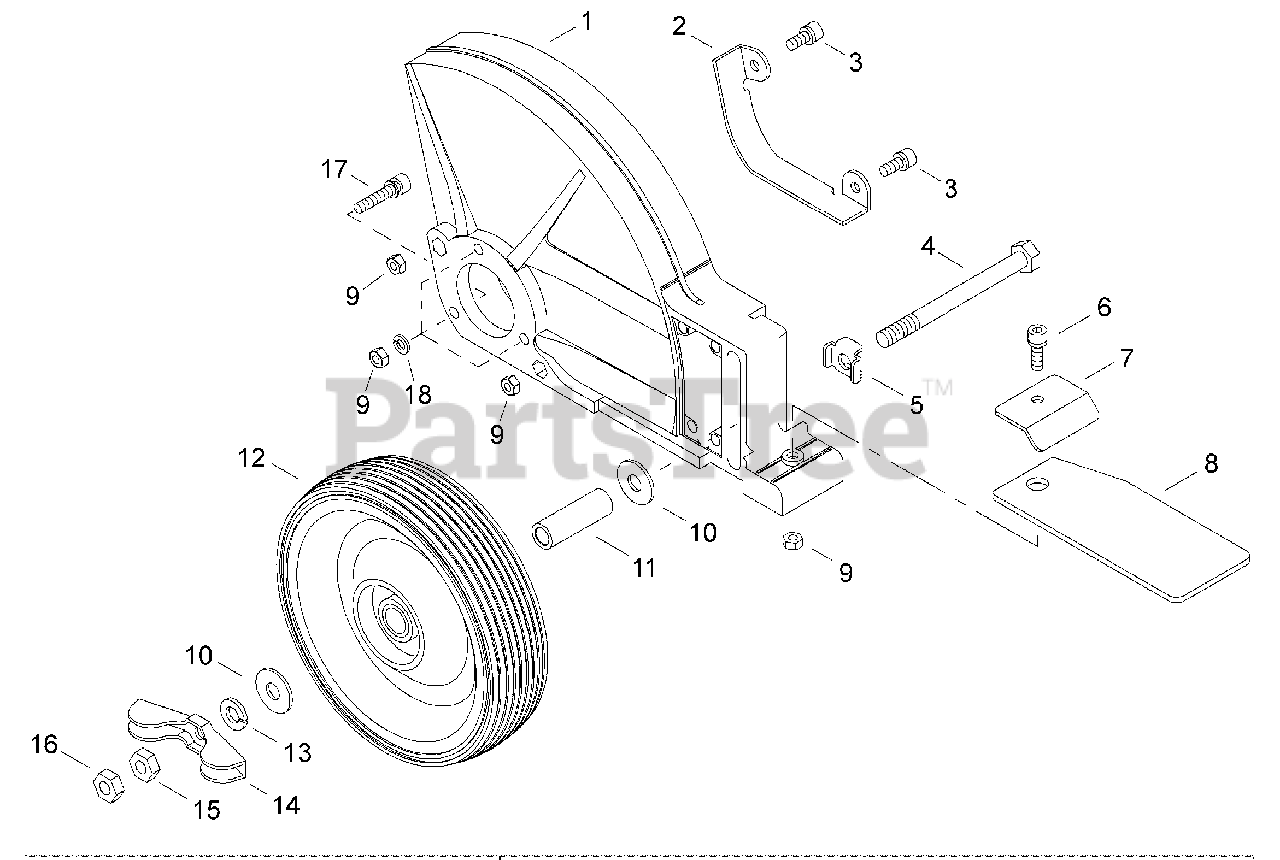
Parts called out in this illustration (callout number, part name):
1	SHIELD, DEBRIS
2	PROTECTOR
3	SCREW - 5X12
4	BOLT - 8X90
5	BRACKET
6	SCREW - 5X16
7	PLATE
8	DEFLECTOR
9	NUT - 5
10	WASHER
11	COLLAR
12	WHEEL
13	LOCKWASHER - 8
14	WINGNUT
15	NUT - 8
16	LOCKNUT
17	SCREW - 5X25
18	LOCKWASHER - 5
